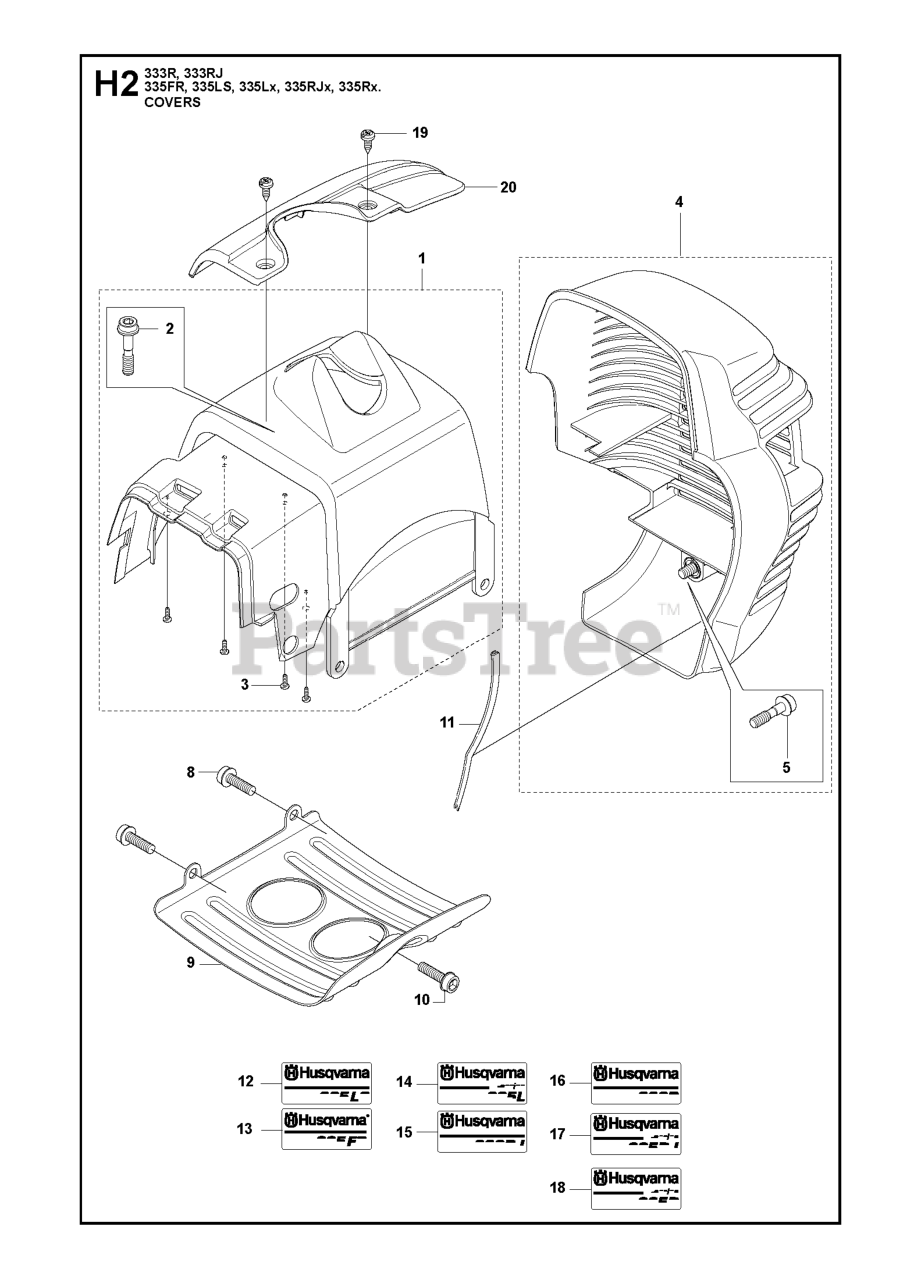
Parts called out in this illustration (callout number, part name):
1	CYLINDER COVER
2	SCREW IHSCFMO
4	HEAT PROTECTOR
5	SCREW IHSCFMO
12	DECAL
13	LABEL
14	DECAL CYLINDER COVER
15	DECAL CYLINDER COVER
16	DECAL
17	DECAL CYLINDER COVER
18	DECAL CYLINDER COVER
19	SCREW CCRPANT ST4.2X9.5 DS
20	ARM PROTECTION
